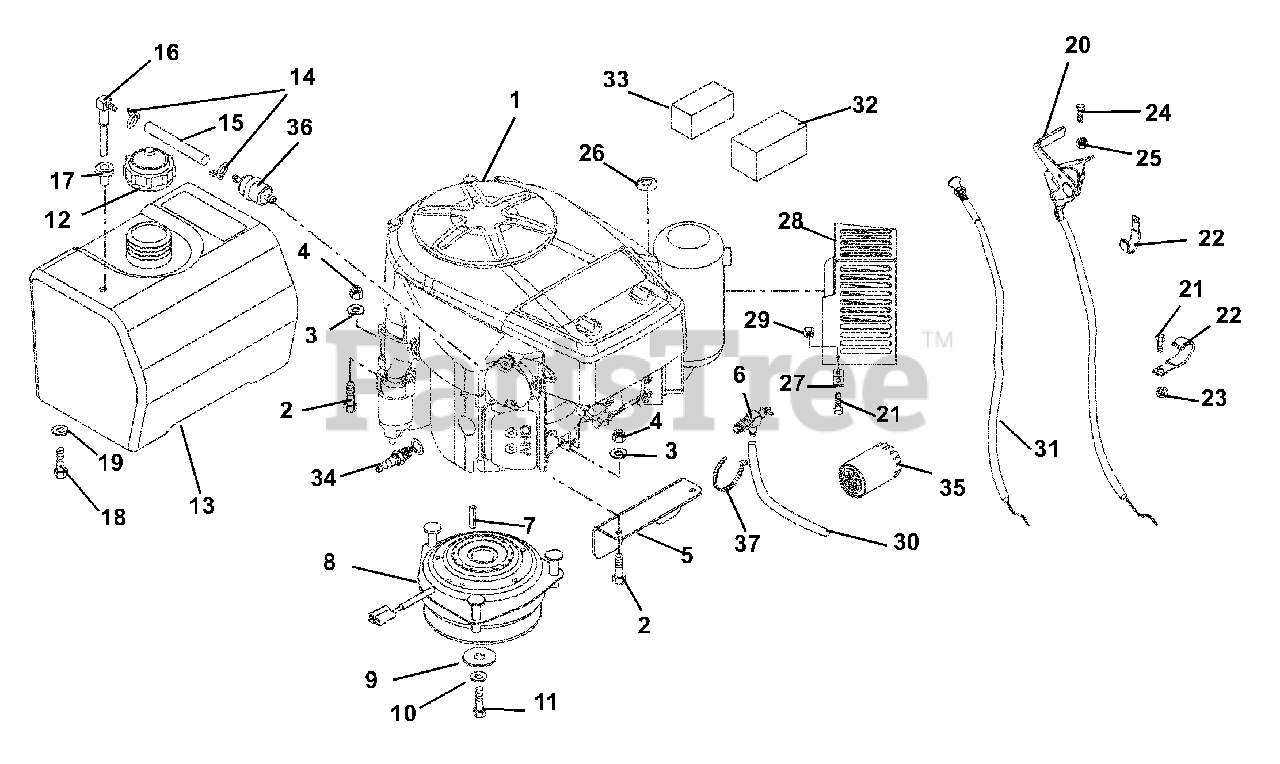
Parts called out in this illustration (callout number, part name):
1	Engine, 15 HP Kawasaki
2	Bolt, Hex .31-18 x 1.75 Grade 5
3	Washer, Locking .31 x .078 Regular
4	Nut, Hex .31-18
5	Bracket, Clutch
6	Valve, Oil Drain
7	Key, Square .25 x 1.25 x 25 SAE 8630 OR SAE 1035
8	Clutch, Electric
9	Washer, Flat Steel .469 x 2.00 x .25
10	Washer, Locking .44 x .109 Regular
11	Bolt, Hex .44-20 x 3.00 Grade 5
12	Cap, Fuel
13	Tank, Fuel
14	Clamp, Hose Wire .49/.51 x .116
15	Gas Line, Bulk .25 I.D.
16	Fitting, Tank
17	Bushing
18	Bolt, Hex .38-16 x .75 Grade 5
19	Washer, Locking .38 x .094 Regular
20	Cable, Throttle with Liner
21	Bolt, Hex .31-18 x .75 Grade 5
22	J-Clamp
23	Nut, Locking Nylon .312-18
24	Screw, Machine 10-24 x .75 Hex Washer Head
25	Nut, Locking Nylon 10-24 with Insert
26	Washer, Flat Steel .38 x .87 x .179
27	Bracket, Muffler Guard
28	Guard, Muffler
29	Nut, Locking Center .31-18
30	Tube, Oil Drain
31	Control, Choke
32	Filter, Air Paper
33	Filter, Air Foam
34	Spark Plug
35	Filter, Oil
36	Filter, Fuel - Kawasaki
37	Cable Tie Large 5.5"
